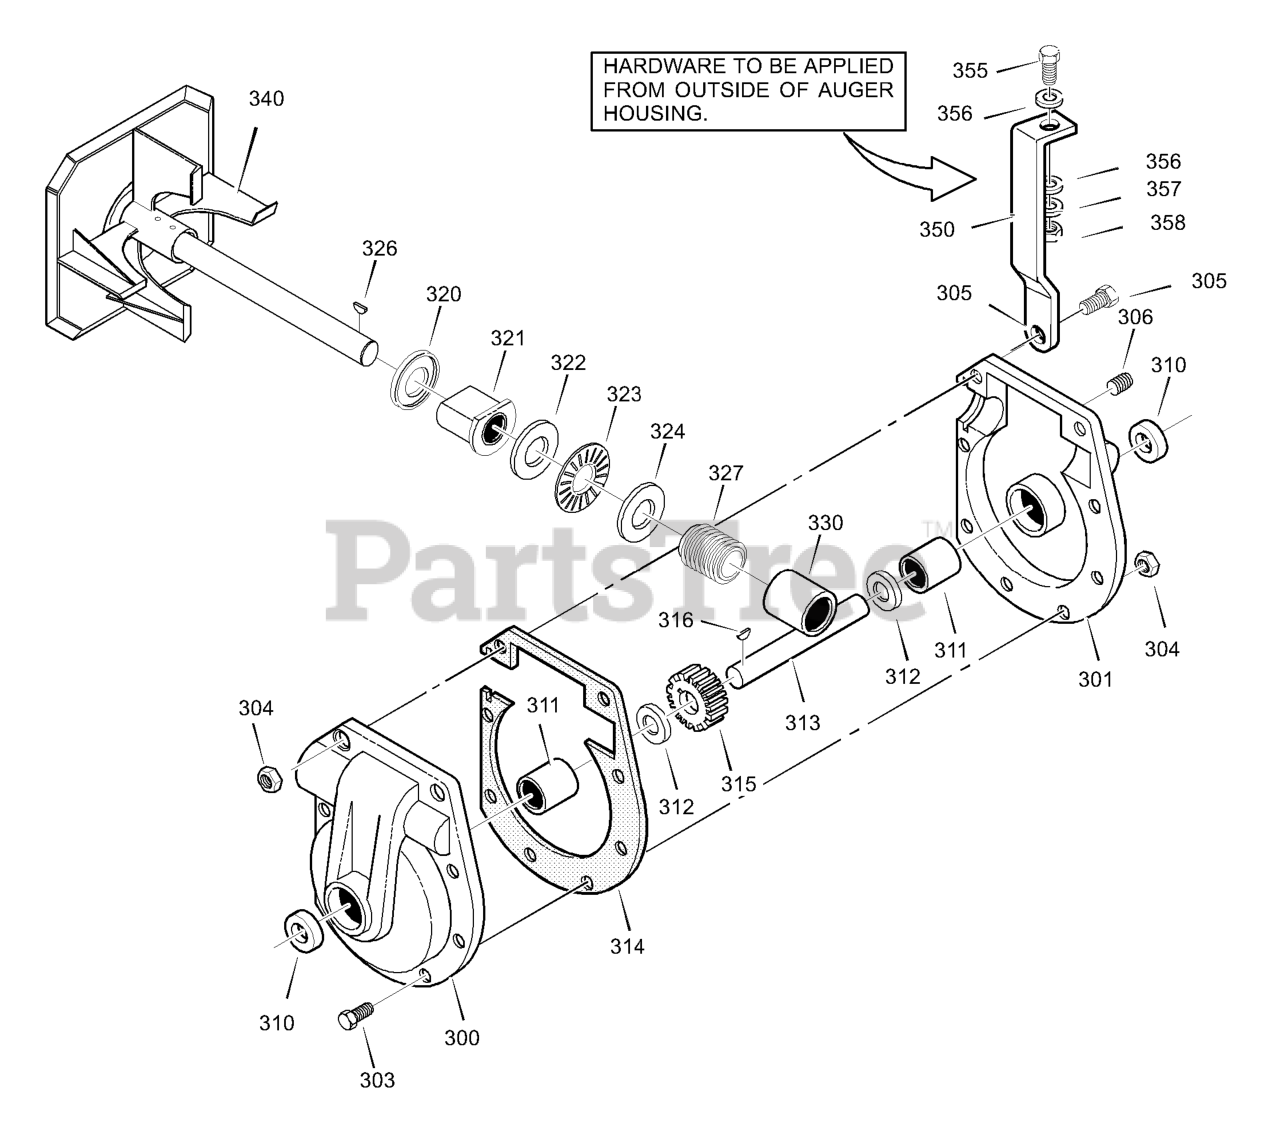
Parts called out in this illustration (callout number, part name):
300	CASE, GEAR, RH
301	CASE, GEAR, LH
303	SCREW, 5/16-24 x 1.00
304	NUT, 5/16-24
305	SCREW, 5/16-24 x 1.75
306	PLUG, PIPE 1/4-18
310	SEAL, OIL
311	BEARING, SLEEVE
312	WASHER, FLAT
313	SHAFT, AUGER OUTPUT
314	GASKET, GEAR BOX
315	GEAR, WORM
316	KEY, WOODRUFF #61
320	RING, QUAD.
321	BEARING, FL
323	BEARING, ROLLER
350	LF BRACE, GEAR BOX
352	NUT, 5/16-24
355	SCREW 5/16-18X1.25
356	WASHER
357	WASHER
358	NUT 5/16-18
